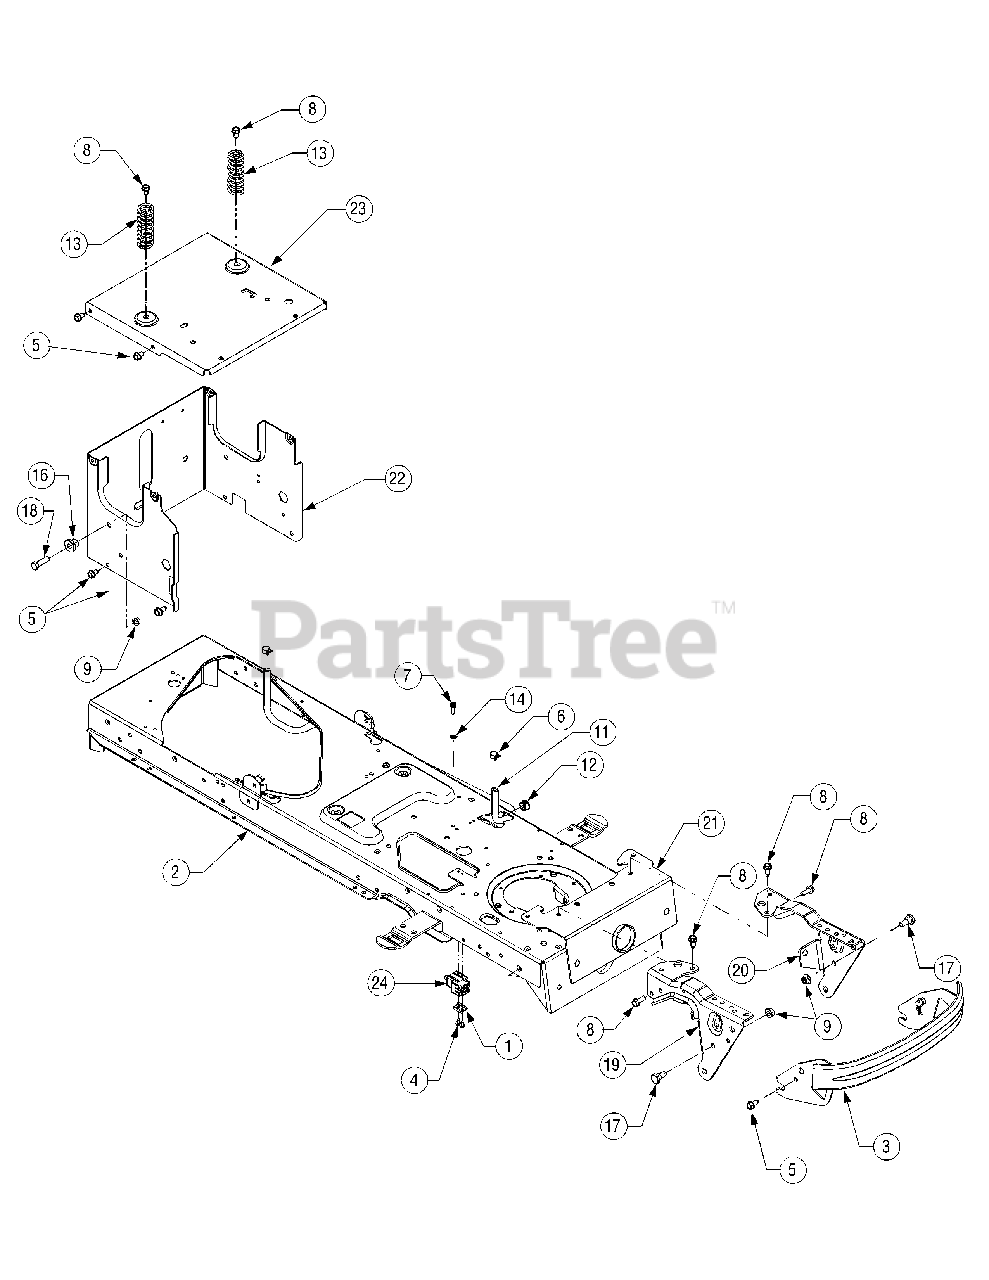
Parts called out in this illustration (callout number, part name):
1	Plate, Switch
4	Screw, Hex Head, 10-16 x .5
5	Screw, Self-tapping, 5/16-18, 0.75
6	Clamp, Hose, .490 Dia.
7	Screw, Hex Wash. Hd. Tapp, 1/4-20 x 0.625
8	Screw, Self-tapping, 5/16-12, 0.75
9	Nut, Nylon Lock, 3/8-16
10	Screw, Hex Wash. Tapp, 5/16-18 x .5
11	Fuel Line, Low Permeation, 29"
12	Snap Bushing
13	Spring, Compression, 1.28 OD x 3.125
14	Washer, Lock, Ext 1/4
16	Shoulder Spacer
17	SHOULDER SCREW .498 DIA x .340
18	Hex Screw 3/8-16 x 1.25
22	Frame, Upper
24	Switch, Interlock
